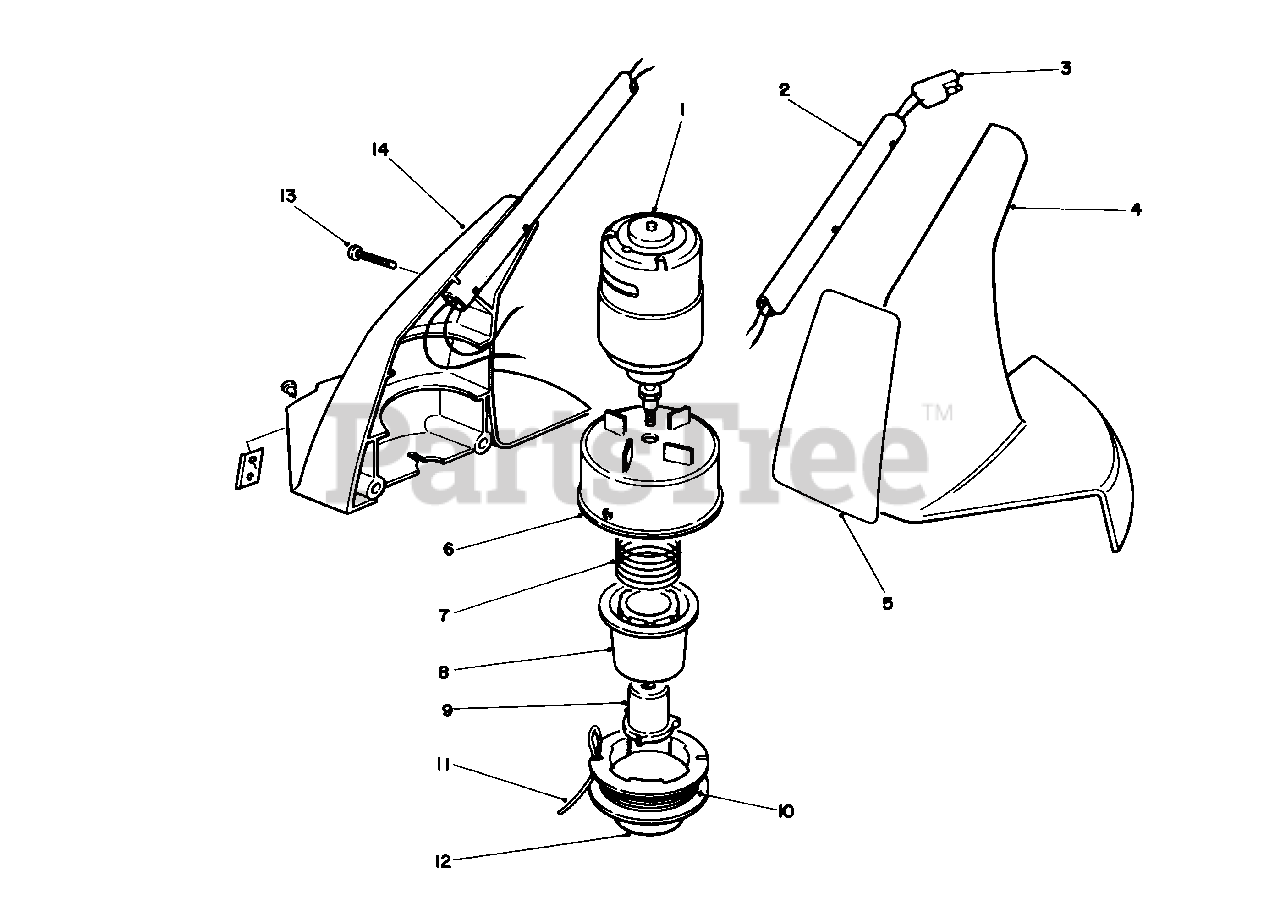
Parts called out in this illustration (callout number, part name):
2	Extension-Handle
3	Wiring Harness-Lower
4	Housing-Motor L.H.
5	Decal-Cordless
6	Drum w/Eyelet
10	Line-Cutting 12' .050 Dia. Prewound Spool
11	Spool-Empty
12	Line-Cutting 30' .050 Dia. in Coil
14	Housing-Motor R.H.
